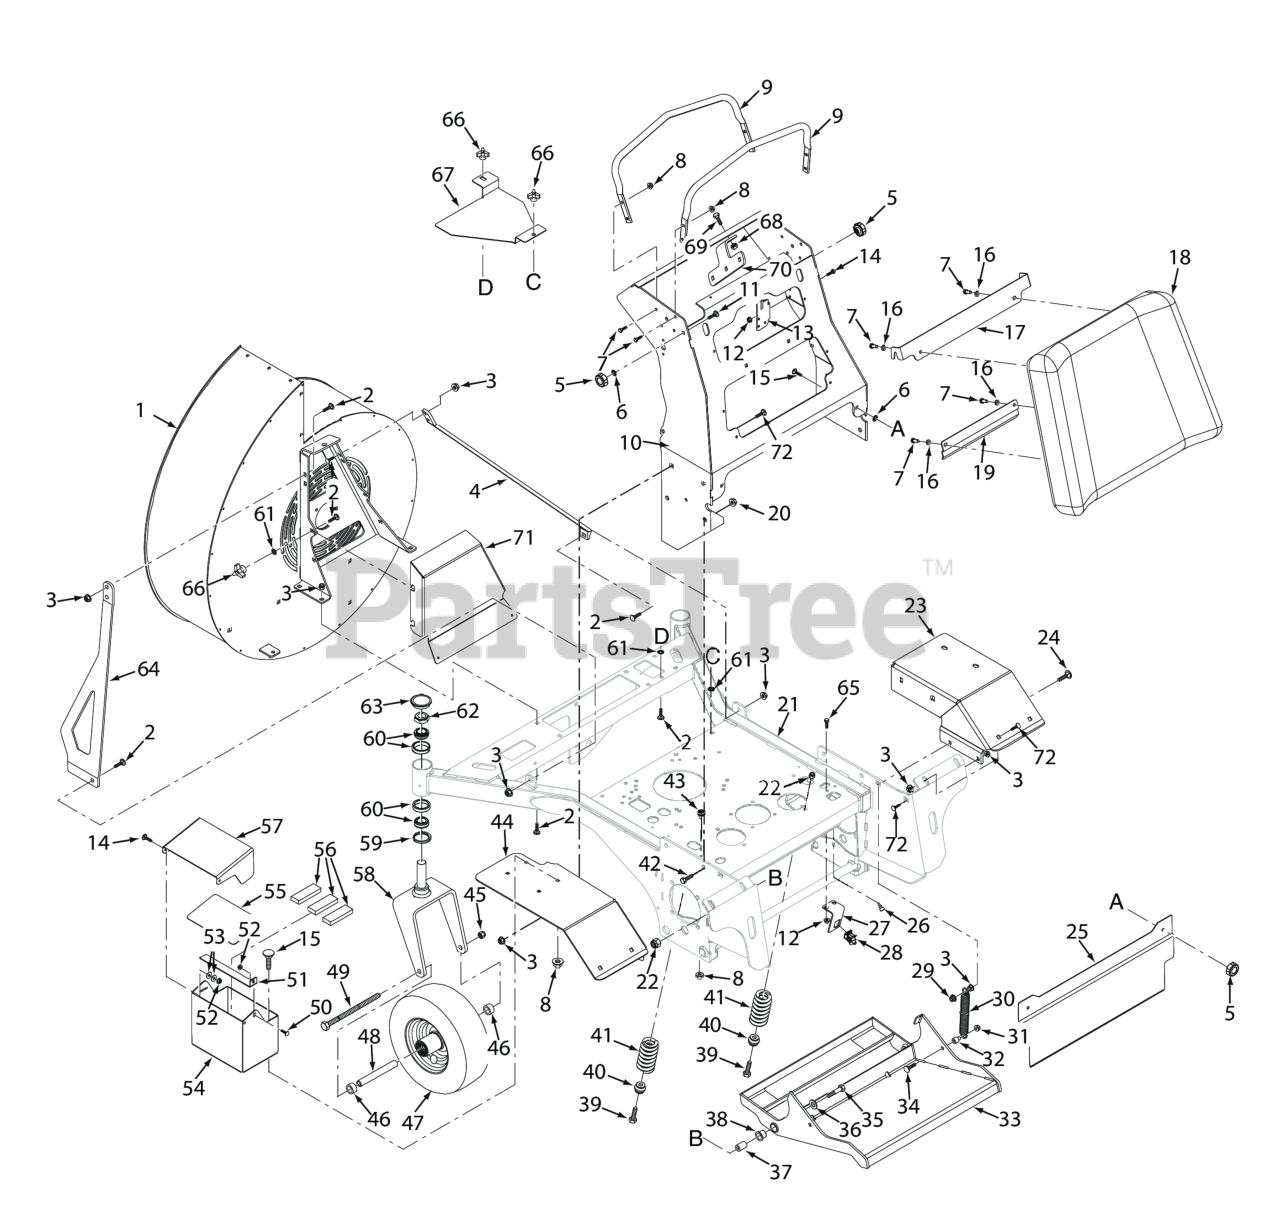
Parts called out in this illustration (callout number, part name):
1	Blower Housing, With Decal
2	Carriage Bolt, 3/8-16 x 1.0"
3	NUT, 3/8-16 SERRATED FLANGE HEX HEAD
4	RH Support Bar, Blower
5	Knob, 5/16-18
6	Nut, Push-On 5/16-18
7	BOLT, SERRATED FLANGE HEX HEAD 5/16-18 X 3/4"
8	Nut, Serrated Flange 5/16-18 (Right Front Engine Mounting, Briggs and Kohler Only)
9	Reference Bar
10	Handlebar Weldment, SVRII
11	Bolt, Carriage 5/16-18x1" (large frame units only)
12	NUT, 1/4-20 SERRATED FLANGE HEX HEAD
13	Bracket, Neutral Switch
14	BOLT, HEX HEAD, 1/4-20 X 3/4 GR.5
15	Bolt, 5/16-18 x .75 RHSN Carriage
16	Lockwasher, 5/16 (.317 x .586 x .078) Helical Spring
17	Bracket, Knee Pad - Upper
18	Operator Pad Assy, SVRII
19	Bracket, Knee Pad - Lower
20	Locknut, 1/2-13 Spiral Lock
21	Mainframe Assembly, With Decals
22	HEX NUT, ELASTIC STOP LOCK, 3/8-16
23	Fender, RH
24	Bolt, RDHD Carr. 3/8-16 x 1-1/2 (52" & 61")
25	Guard, Foot
26	BUMPER, PLUG
27	Switch Bracket, Operator Presence
28	SWITCH, NEUTRAL INTERLOCK
29	Nut, Flange Elastic Stop Nut, 3/8-16
30	Spring,Counter Balance
31	Nut, Flange Head Elastic Stop 5/16-18
32	Spacer, Pump Dampener
33	Footplate Assy, SVRII
34	Bolt, Carriage 5/16-18 x 1-1/2"
35	Capscrew, Hex Head 3/8-16 x 2.0"
36	Flatwasher, 3/8" Special (.391 x .938 x .105)
37	Yoke, Front Caster Wheel
38	Bearing, .750 I.D. Plastic
39	Bolt, Hex Head 3/8-16 x 1-3/4" (Kohler EFI)
40	Mount, Spring
41	Spring, Suspension Platform
42	Capscrew, 1/2-13 x 1" Serrated Flange Hex Head
43	Bumper, Rubber 5/16-18 x 5/8"
44	Fender, LH
45	HEX LOCKNUT, ELASTIC STOP, 1/2-13
46	Spacer, Caster Wheel
47	Wheel Assy, 52V (Incl. items 20, 54, 55)
48	Sleeve, Caster Wheel (48 / 52)
49	Bolt, Hex Head 1/2-13 x 7-1/2" (48"/52")
50	Bolt, Carriage 1/4-20 x 1/2"
51	Battery Box Latch
52	HEX, NUT, ELASTIC STOP LOCK, 1/4-20
53	Flatwasher, 1/4" (.312 x .750 x .065")
54	Battery Box, Lower
55	Insulation, Battery Cover (Gas Only)
56	PAD, BATTERY SUPPORT
57	Battery Box, Upper
58	Yoke, Front Caster Wheel (48"/52")
59	Seal, 2.00" O.D. x 1.625" Bore
60	BEARING & CUP, TAPERED SPINDLE
61	Nut, Push-On - 3/8" Dia.
62	Nut, Hex Elastic Stop 1.0"-14
63	Cap, Grease
64	LH Support Bar, Blower
65	Serr. Fl. Hex Head CPSCR, 1/4-20 x 3/4"
66	Wing Nut, 3/8-16 (Small) Top side
67	Belt Cover, Gearbox
68	Nut, Flanged Elastic Stop 1/4-20
69	Screw, Self-Tapping 1/4-20 x 3/4
70	Mounting Bracket, Relays
71	Belt Cover, Blower
72	Bolt, Carriage 3/8-16 x 3/4"
